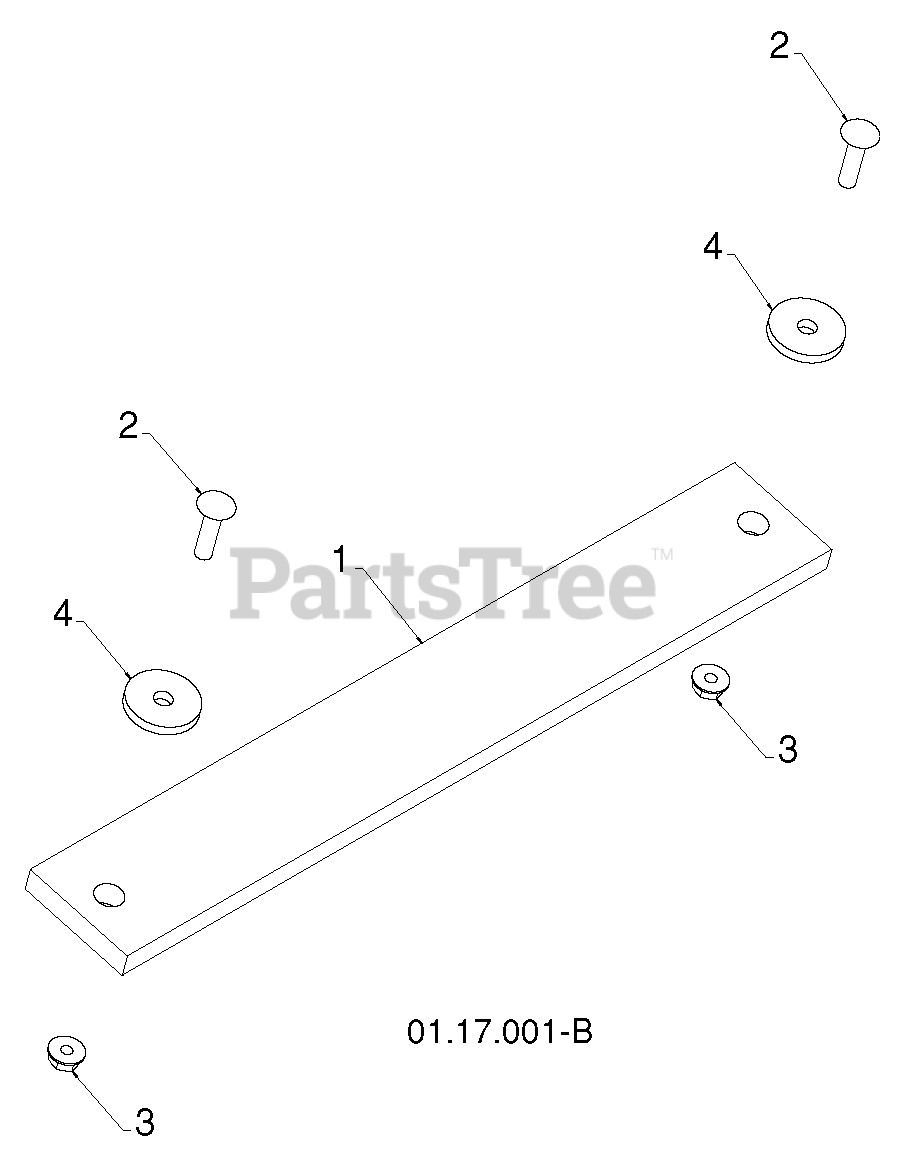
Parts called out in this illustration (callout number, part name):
1	WEIGHT.AUGER.HSG.24
2	BOLT.CARRIAGE.5/16-18
3	NUT.LOCK.5/16-18
4	WASHER.FLAT.34X1.38X22
